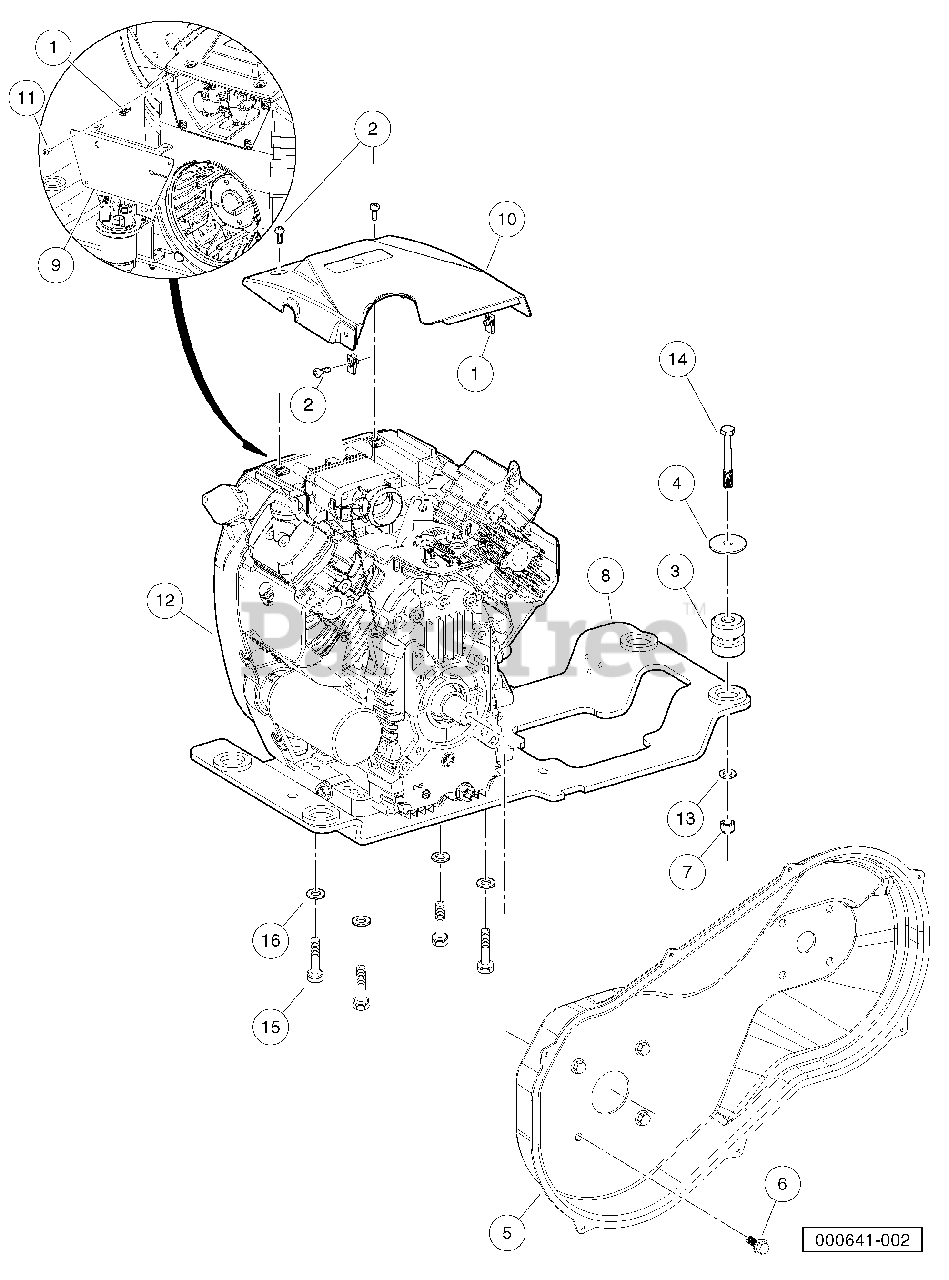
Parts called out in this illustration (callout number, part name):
1	U-nut, M6-1.0 Prev Torque
2	Screw, M6 Torx Bttn Hd Sems
3	Isolator Ring and Bushing
4	Washer, Snubbing, Ring N Bush
5	Cover, CVT Inner, FH680D
6	Bolt Flanged Head, 3/8-16x1.0 with Loctite
7	Locknut, M12x1.75 Nylon Insert
8	Weldment, Eng Mnt, Kaw, Fh680d
9	Engine, Front Cover, Fh680d
10	Cover, Engine, Top
11	Screw, Pn Hd Blk, 10-16 X .625
12	Engine, Kawasaki, FH680D
13	Washer, M12 Hard
14	Bolt, M12 X 1.75 X 90
15	Bolt, M10 X 1.5 X 60
16	Washer, M10 Hard
